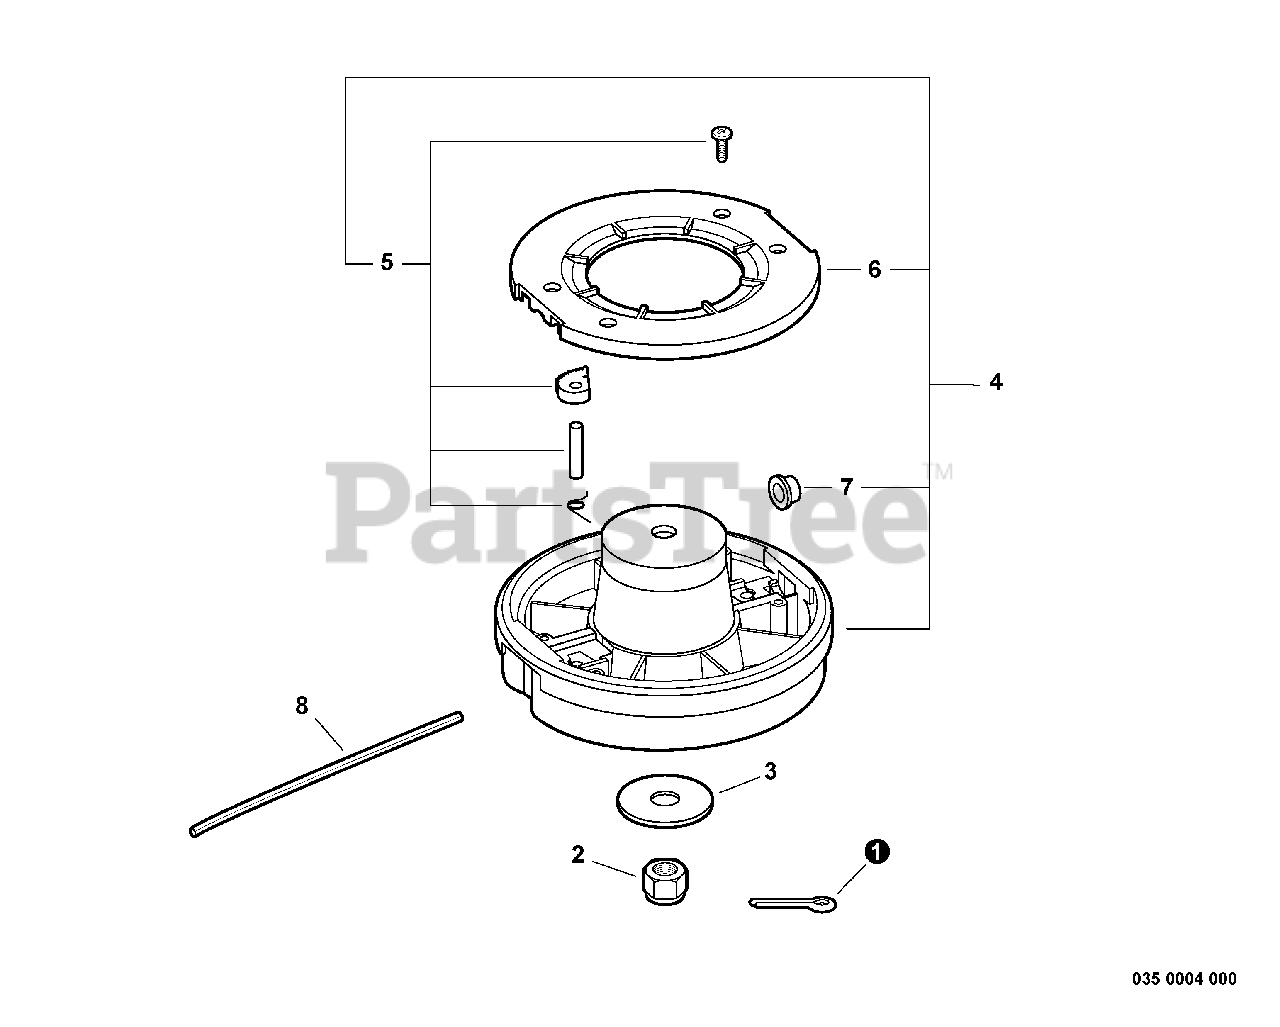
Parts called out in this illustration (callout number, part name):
1	PIN, SPLIT
2	LOCKNUT - LEFT HAND
3	WASHER - 8
4	TWO LINE RAPID LOADER ATTACHMENT
5	REPAIR KIT
6	COVER - TOP
7	EYELET
8	LINE, TRIMMER - 0.095 DIA
